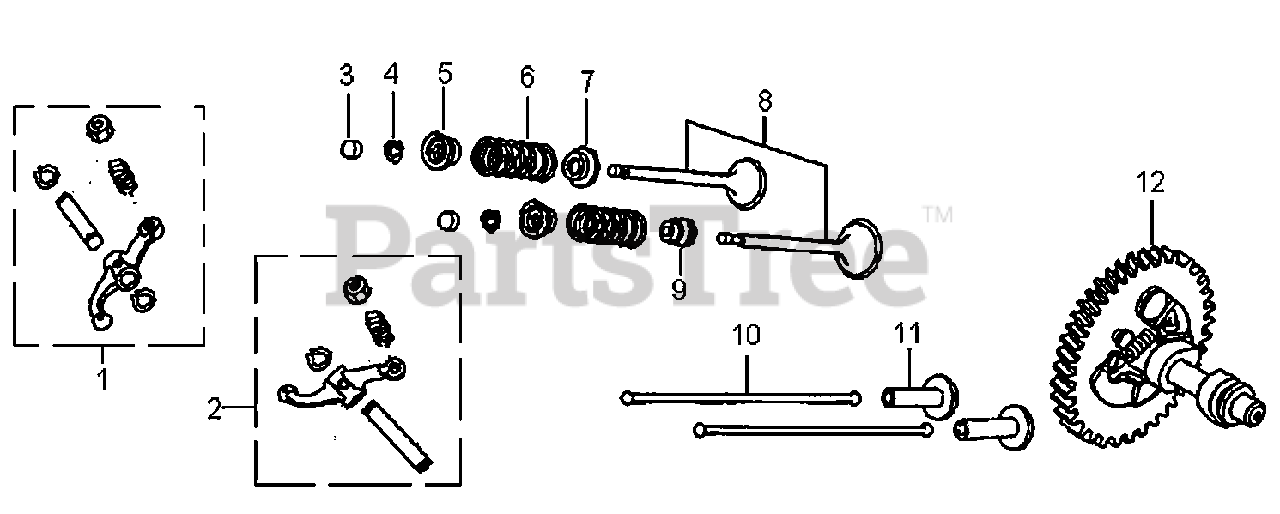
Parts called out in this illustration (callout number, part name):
1	ROCKER ARM ASSY.
2	ROCKER ARM ASSY.
3	ROTATOR, VALVE
4	VALVE LOCKER
5	RETAINER, VALVE SPRING
6	SPRING, VALVE
7	SEAT, VALVE SPRING
8	VALVE ASSY.
9	SEAL, VALVE STEM
11	LIFTER, VALVE
12	CAMSHAFT ASSY
